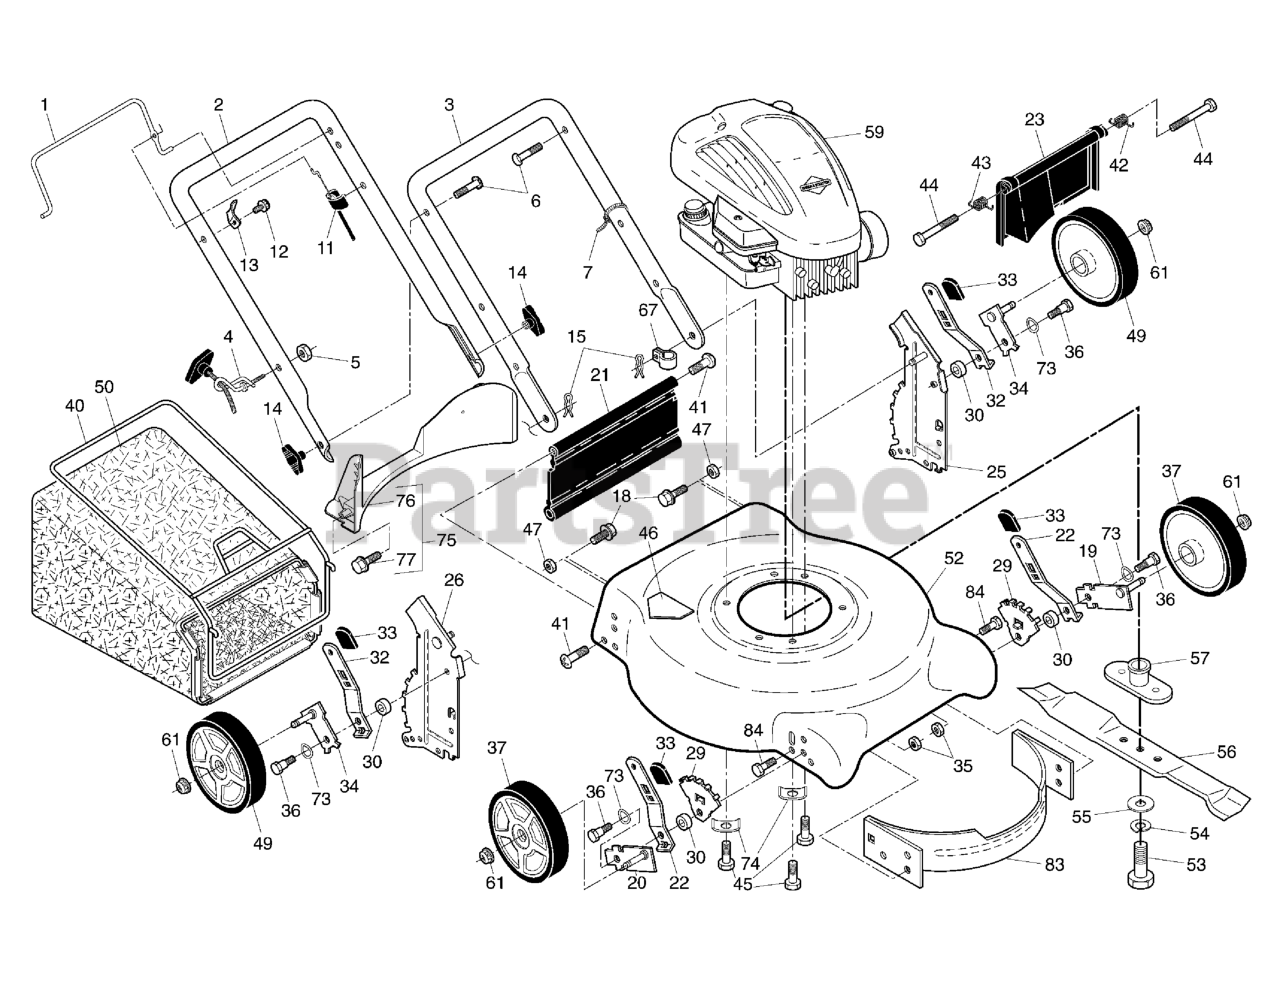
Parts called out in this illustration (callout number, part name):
1	Control Bar
2	Upper Handle
3	Lower Handle
4	Rope Guide
5	Nut, Hex
6	Handle Bolt
7	Wire Tie
11	Engine Zone Control Cable
12	Hex Washer Head Screw
13	Up-Stop Bracket
14	Handle Knob
15	Hairpin Cotter
18	Screw 1/4-20 x 3/8
19	Axle Arm Assembly, Front, LH
20	Axle Arm Assembly, Front, RH
21	Kit, Rear Skirt
22	Selector Spring, Front
23	Rear Door Assembly
25	Handle Bracket Assembly, LH
26	Handle Bracket Assembly, RH
29	Wheel Adjusting Bracket
30	Spacer
32	Selector Spring, Rear
33	Selector Knob
34	Axle Arm Assembly, Rear
35	Locknut, Hex
36	Shoulder Bolt 5/16-18
37	Wheel & Tire Assembly, Front
40	Frame, Grass Bag
41	Hinge Screw
42	Spring, Rear Door, LH
43	Spring, Rear Door, RH
44	Bolt, Rear Skirt
45	Screw, Hex Head, Threaded, Rolled, 3/8-16 x 1
46	Danger Decal
47	Nut, Hex 5/16-18
49	Wheel & Tire Assembly, Rear
50	Grass Bag
52	** Kit, Housing Assembly (Includes Ref. 46)
53	Hex Head Screw, 3/8-24 x 1-3/8, G8
54	Helical Lockwasher
55	Hardened Washer
56	21" Blade
57	Blade Adapter
59	* ENGINE, Briggs & Stratton
61	Locknut, Hex, Flanged
67	Clip, Cable
73	Washer, Flat
74	Washer, Special, Engine
75	Kit, Rear Baffle (Includes 3 Screws)
76	Baffle, Rear
77	Screw, Rear Baffle
83	Baffle, Front
84	Screw, Front Baffle
